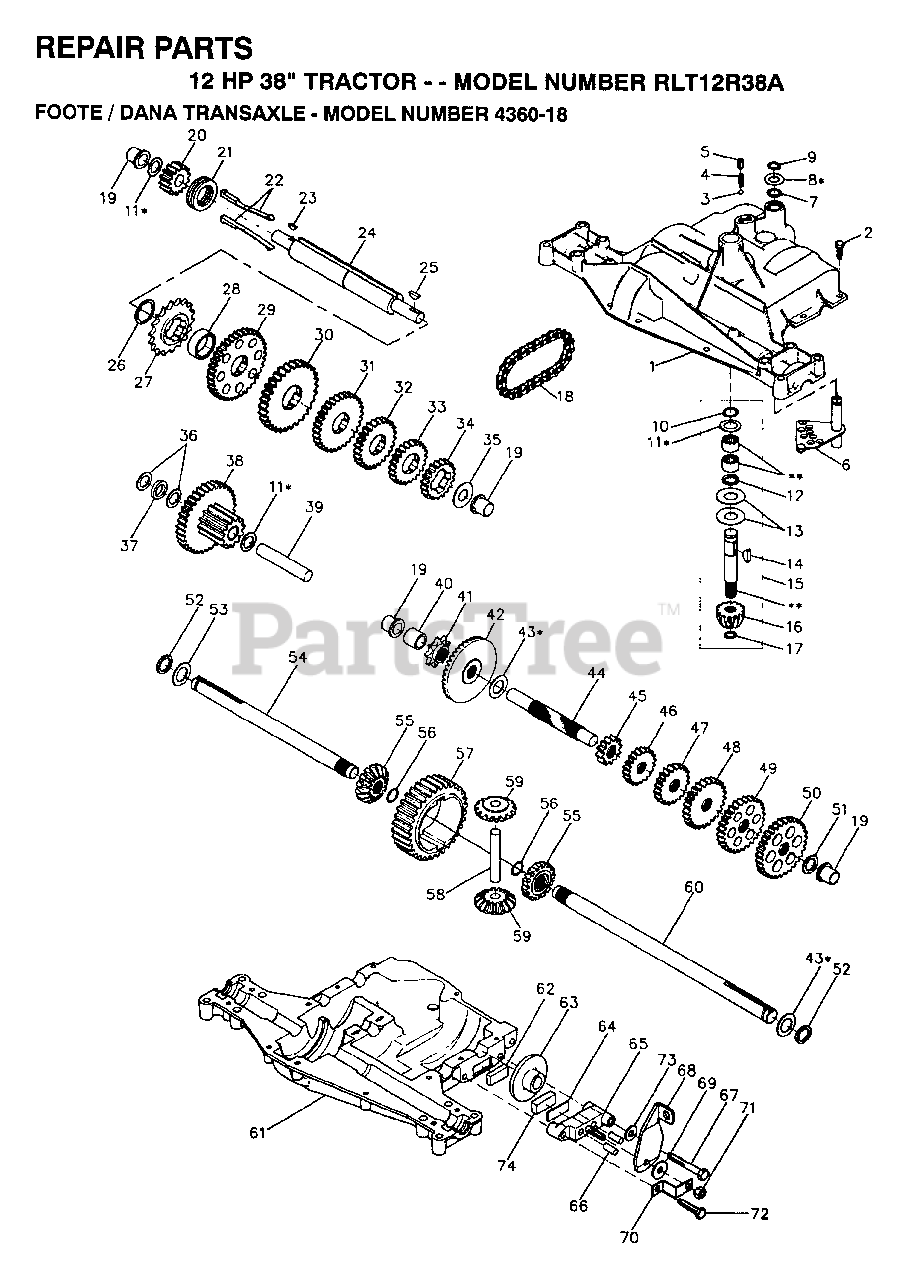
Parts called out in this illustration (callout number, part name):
3	"DETENT, BALL(68003)"
4	"SPRING, DETENT LT"
5	"SCREW, SET LT"
7	ORING T
9	RETAINING RING LT
10	RETAINING RING LT
11	WASHER
12	O-RING T
13	WASHER T
14	WOODRUFF KEY
15	IMPUT KIT T
16	PINION 14T T
17	"RING,RETAINING LT"
18	"CHAIN,24 PTCH LT"
19	BEARING.FLNG.5510
22	KEY T
25	WOODRUFF KEY
26	"RING,RETAINING LT"
27	SPROCKET 18T T
28	SPACER YT
29	KIT.GEAR.12/37TH
32	GEAR 25T LT
33	GEAR SPUR 22 TT
35	"WASHER, PLAIN LT"
36	WASHER 025
37	SPACER
38	ASSM GEAR COMB
39	SHAFT IDLER T
40	SPACER T
41	SPROCKET 9T LT
43	WASHER LT
44	SHAFT T
48	"GEAR, SPUR 25T LT"
49	GEAR 28T T
50	"GEAR, SPUR 31T LT"
51	WASHER 060
53	WASHER 062
55	GEAR 15T T
56	"RING,RETAINING LT"
58	SHAFT T
59	GEAR 1ST T
62	PUCK T
63	BRAKE DISC. T
64	SPACER LT
66	PIN T
67	SCREW T
68	LEVER ACTUATOR
69	WASHER LT
71	NUT.LOCK.5/16-24
72	"SCREW, TAPPING LT"
73	WASHER T
74	PUCK T
